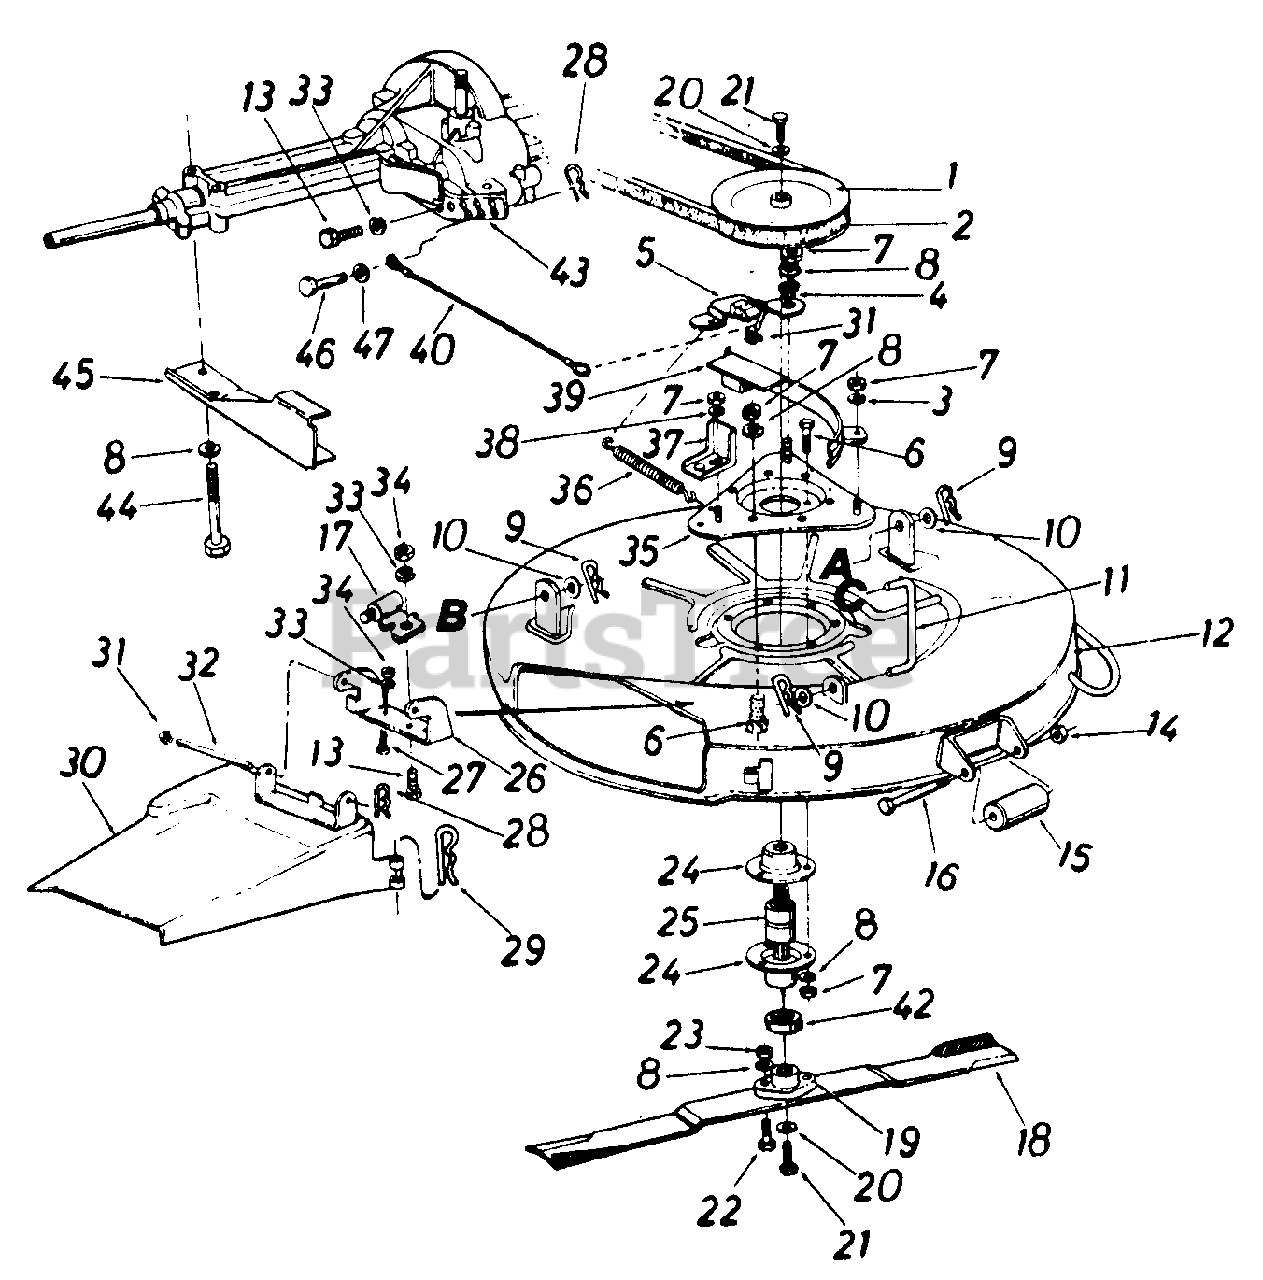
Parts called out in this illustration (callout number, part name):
1	Deck Pulley 7.00" O.D.
2	"V"-Belt 1/2" x 52" Lg.
3	Belleville Washer
4	Shoulder Spacer
5	Blade Brake Brkt. Ass'y.
6	Hex Bolt 5/16-18 x .75" Lg.
7	Hex Nut 5/16-18 Thd.
8	L-Wash. 5/16" I.D.*
9	Intern. Cotter Pin 1/2" Dia.
10	Fl-Wash. .531" I.D. x .930"
11	Deck Link 3.9" Lg.
12	30" Deck Ass'y.
13	Hex Bolt 1/4-20 x .62" Lg.
14	Hex Nut 3/8-16 Thd.
15	Skid Roller
16	Shoulder Bolt .498" Dia. x 4.75"
17	Safety Switch
18	30" Blade
19	Blade Adapter
20	L-Wash. 3/8" I.D.-H.D.
21	Hex Bolt 3/8-24 x .75" Lg.
22	Hex Bolt 5/16-24 x 1.00"*
23	Hex Nut 5/16-24 Thd.*
24	Housing Bearing Spindle
25	Blade Spindle
26	Deck Hinge Brkt.
27	Carriage Bolt 1/4-20 x .62"*
28	Intern. Cotter Pin 5/16" Dia.
29	Cotter Pin
30	Chute Deflector Ass'y.
31	Cap Speed Nut 1/4" Flod
32	Hinge Pin
33	L-Wash. 1/4" I.D.
34	Hex Nut 1/4-20 Thd.*
35	Spindle Mtg. Bracket Ass'y.
36	Extension Spring .38" O.D. x 3.25" Lg.
37	Belt Keeper Ass'y.
38	Belleville Wash. 5/16" I.D.
39	Belt Guard
40	Brake Cable Ass'y.
42	Bearing Guard
43	Lower Inside Belt Guard
44	Hex Bolt 5/16-18 x 2.5" Lg.
45	Lower Outside Belt Guard
46	Clevis Pin 1/4" x 1/2"
47	Fl-Wash. 1/4" I.D. x .50" O.D.
